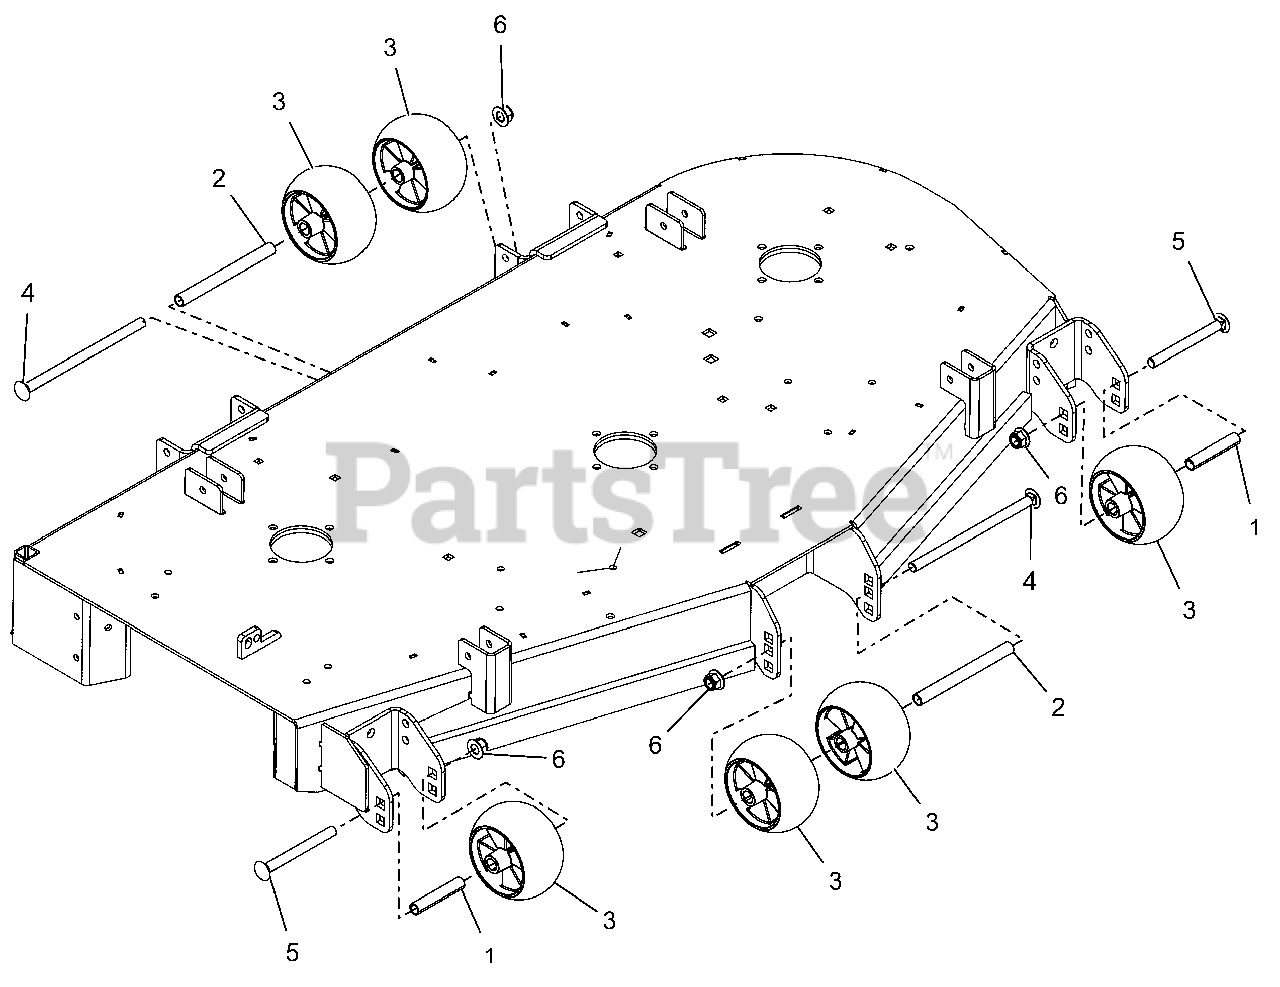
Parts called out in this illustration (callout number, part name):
1	SPACER, .510X.625X3.35
2	SPACER, .510X.625X6.50
3	ANTI-SCALP WHEEL - 5X3 CTR
4	@BLT-RDHDSQNK .50-13X8.50 G5YZ
5	BLT-RDHDSQNK .50-13X5.00 GR5YZ
6	@NUT-LK-NYL-FLG .50-13 YWZC
